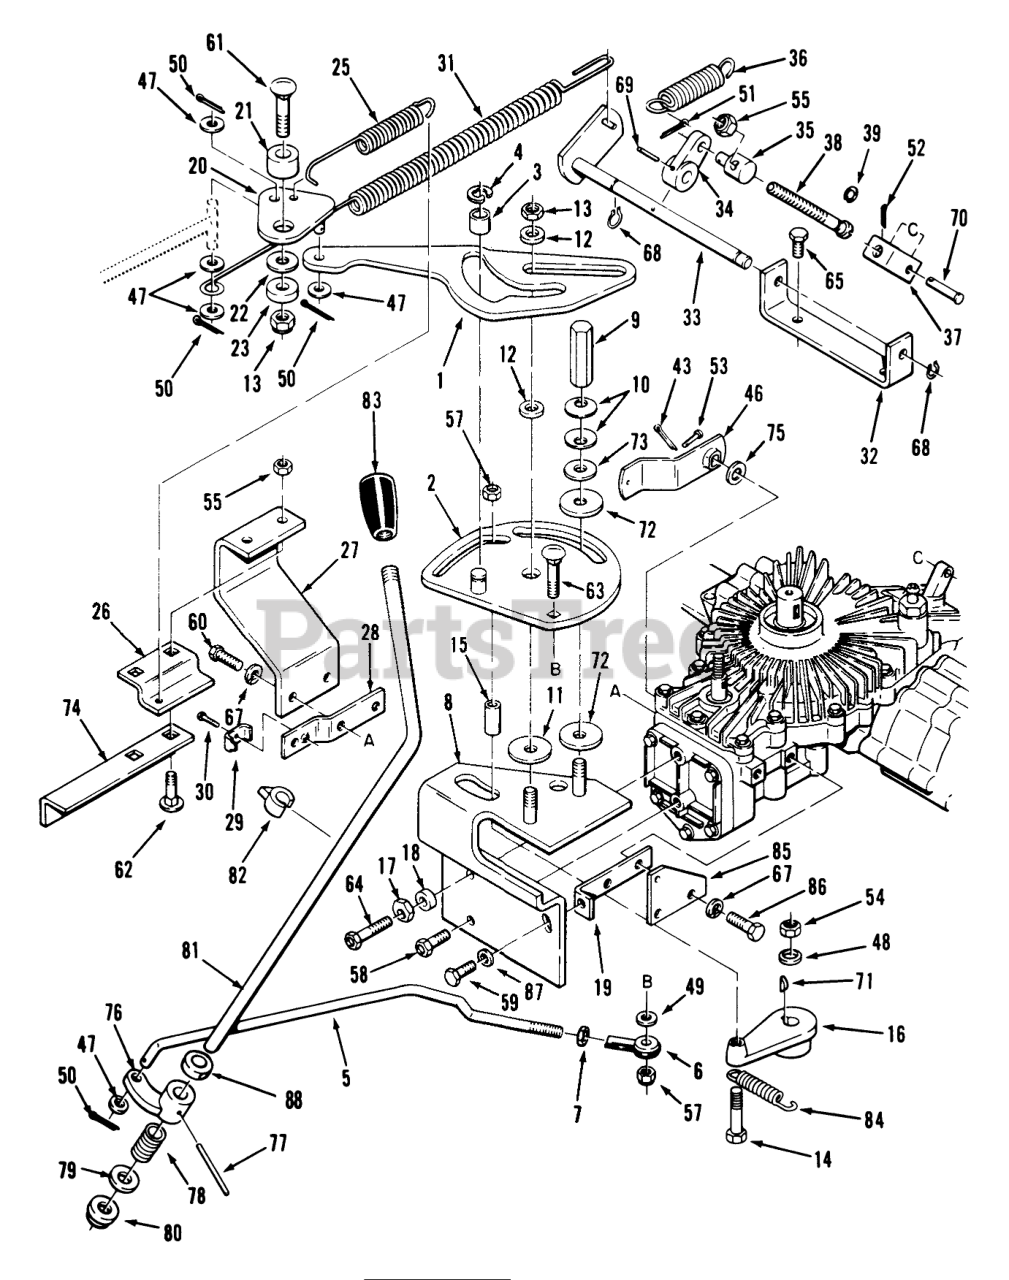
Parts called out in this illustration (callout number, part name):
1	NEUT-RETURN PLATE
2	ASS'Y-CAM PLATE
3	BEARING-CAM RETURN
4	RING-RETAINING, EXTERNAL
5	ROD-SPEED CONTROL
6	ASSY ROD END
7	NUT-JAM
8	ASS'Y-CAM PLATE S R
9	NUT-SPECIAL 3/8 X 2"
10	WASHER-SPRING DISC
11	FRICTION WASHER
12	CAM-SPACER
13	NUT-HEX, JAM
14	HHMS 1/4-20 X 2 1/2
15	SPACER
16	ARM MOTION CONTROL
18	SPACER-GEAR
19	ASS'Y-ANGLE SUPPORT
20	PIVOT PLATE ASSY R
21	SPACER
22	WASHER-SPECIAL
23	SPACER-LIFT LINK
25	SPRING-RETURN
26	BRACKET R
27	BRACKET-TORQUE R
28	PLATE-MOUNTING R
29	CLAMP THROTTLE
30	HWHTRS 10-24 X 1/2
31	SPRING-BRAKE
32	BRACKET
33	ASS'Y-BRAKE PIVOT
34	PLATE
35	TRUNNION-CLUTCH ROD
36	SPRING-BRAKE
37	CLEVIS R
38	BOLT-ADJUSTING
39	RING-CLIP
43	Cotter Pin
46	Plate
47	WASHER-PLAIN
48	WASHER-FLAT
49	WASHER-FLAT
50	PIN-COTTER
51	PIN-COTTER
52	PIN-COTTER
54	NUT-HEX
55	NUT-LOCK, NI
57	NUT-LOCK, NI
58	Bolt
59	SCREW-HH
60	SCREW-HH
61	SCREW-CARR
62	BOLT-CARR
63	SCREW-CARR
64	Bolt
65	Bolt
67	WASHER-LOCK
68	RING - INT 1.25 HSG
69	Pin-Spirol
71	KEY WOODR 1/8X1/2 DI
72	WASHER-FRICTION
73	WASHER-FLAT
74	BRACKET R
75	Washer
76	ARM SHIFTER B
77	SPIROL PIN 7/32X21/2
78	SPRING COMPRESSION
79	SHIM-WASHER
80	BUSHING-NYLINER
81	ROD-SHIFT LEVER
82	POINTER
84	SPRING
85	BRACKET-SPRING
86	SCREW-HH
87	Collar
88	COLLAR
